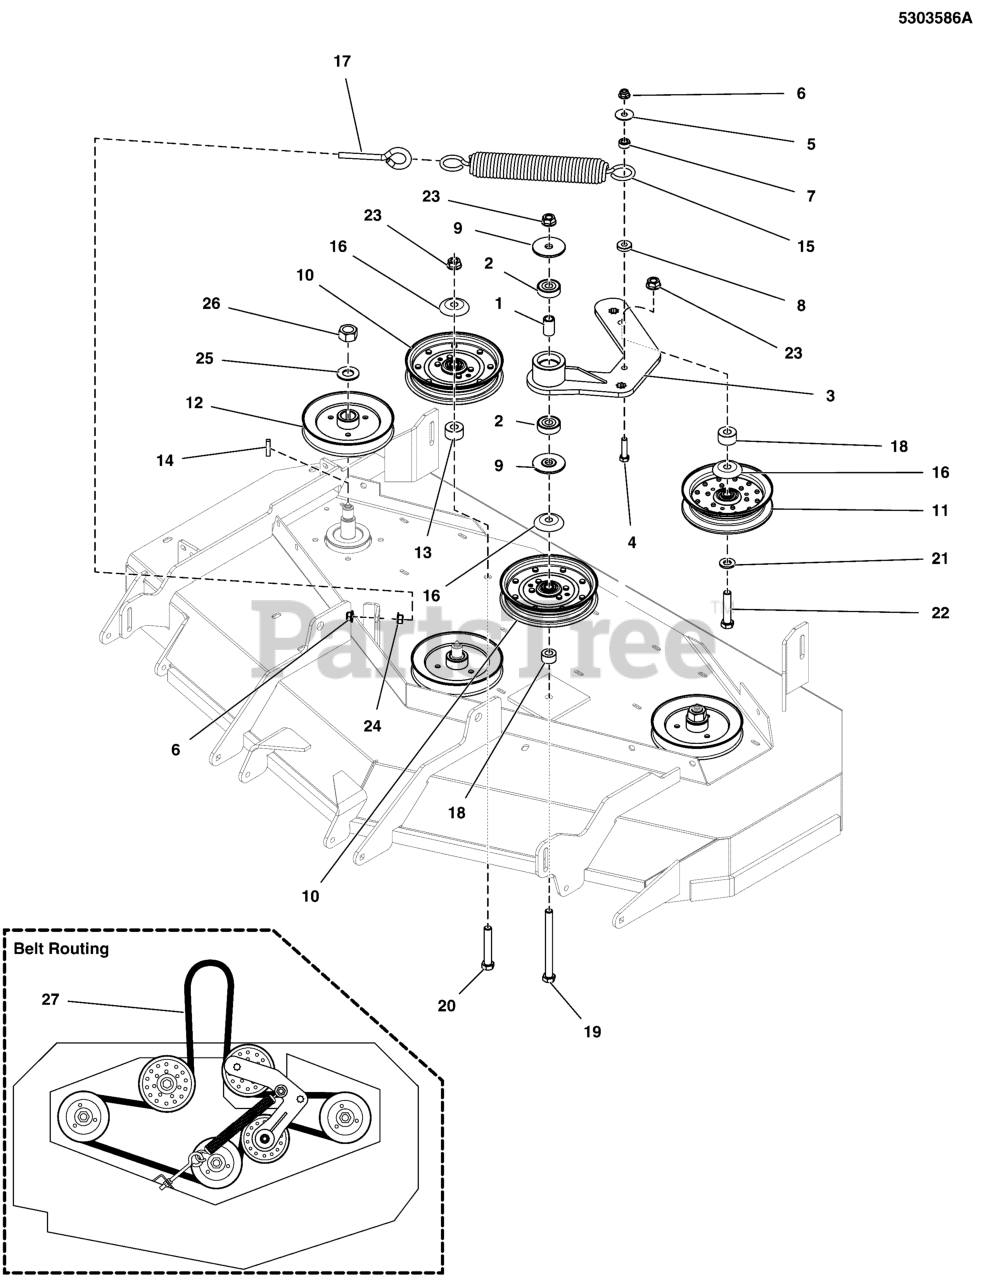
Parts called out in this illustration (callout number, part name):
1	SPACER, .51 X .75 X 1.22, PM CZ
2	BEARING, 6203-1/2", SEALED
3	WELD, IDLER ARM,CUTTER DECKS - BLK
4	BOLT, 3/8-16 X 1-1/2" GD5 CZ
5	WASHER-3/8 FENDER
6	NUT, 3/8-16 HEX NYLOCK FLANGE
7	SPACER, .39 X .75 X .38
8	SPACER, .39 X 1.00 X .25
9	SPACER, IDLER ARM, 1/2 X 2.25
12	PULLEY, 5.926 OVER BALL
13	SPACER, .52 X 1.25 X .70, CZ
14	KEY, 1/4 SQ X 1-1/4
15	SPRING, EXT, 1.5ODX12.25X.234WIRE BLK
16	SHIELD, PULLEY BEARING, CZ
17	EYEBOLT, 3/8-16 X 4, 2.13THRD, .75EYE, C
18	SPACER, .52 X 1.00 X .56, CZ
19	BOLT, 1/2-13 X 5-1/2 GD5 CZ
20	BOLT, 1/2-13 X 3" GD5 CZ
21	WASHER, 1/2 GD9 CZ
22	BOLT, 1/2-13 X 2-1/2" GD5 CZ
23	NUT, Hex Flange, Nylock, 1/2-13
24	NUT, 3/8-16 HEX SERRATED FLANGE
25	WASHER, 3/4 BELLEVILLE
26	NUT, 3/4-16 HEX
27	BELT, 5V, 162.40"EL, ARAMID WRPD, RC
